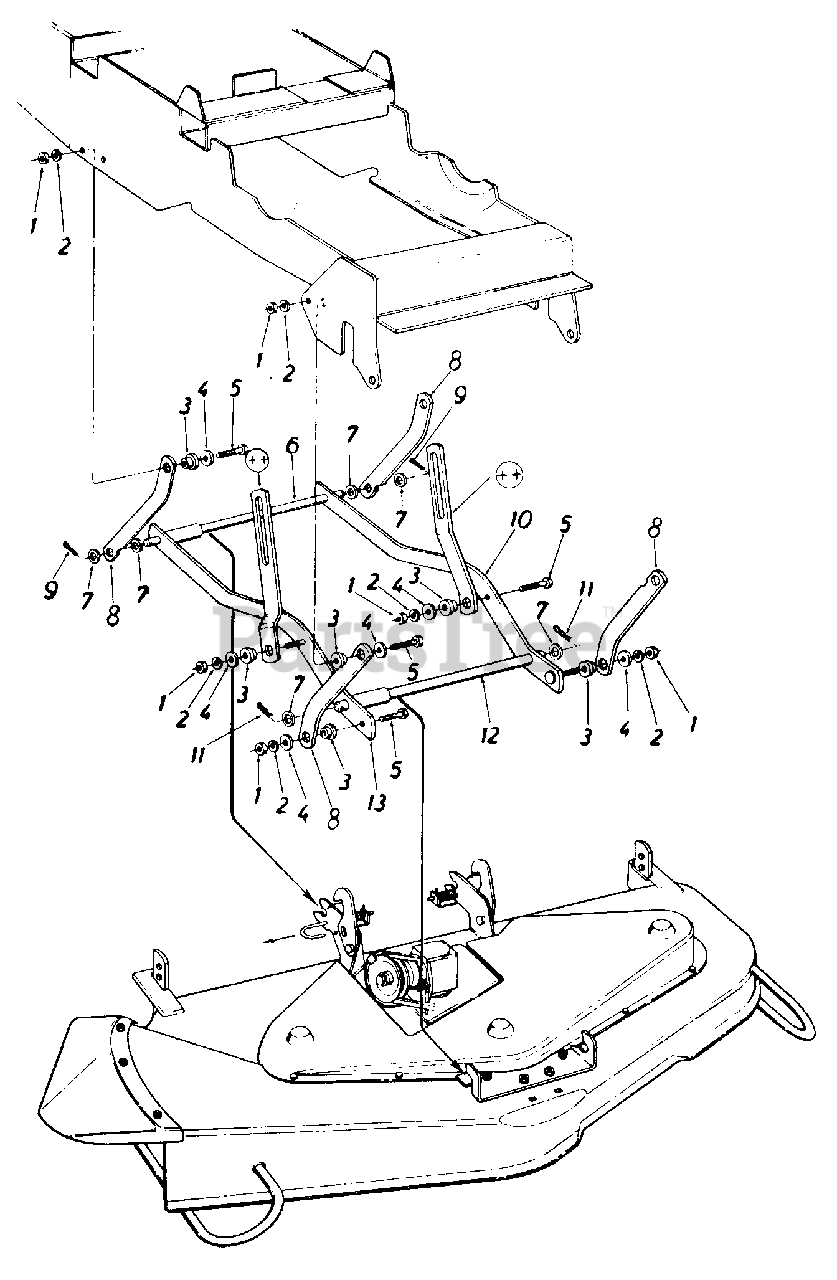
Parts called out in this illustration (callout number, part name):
1	Hex Nut 3/8-24 Thd .*
2	L.-Wash. 3/8" Scr. Heavy Duty
3	Fl.-Wash. 3/8" I.D. x 1.0" O.D.
4	Shoulder Spacer . x 1.0" O.D.
5	Hex Scr. 3/8-24 x 1.50" Lg. Grade 5
6	Cross Shaft Ass'y.-Rear
7	Fl.-Wash. 5/8" I.D. x 1-1/8"O.D.
10	Lift Arm Link-L.H.
11	Hair Pin Cotter
12	Cross Shaft Ass'y.-Front
13	Lift Arm Link Ass'y.-R.H.
